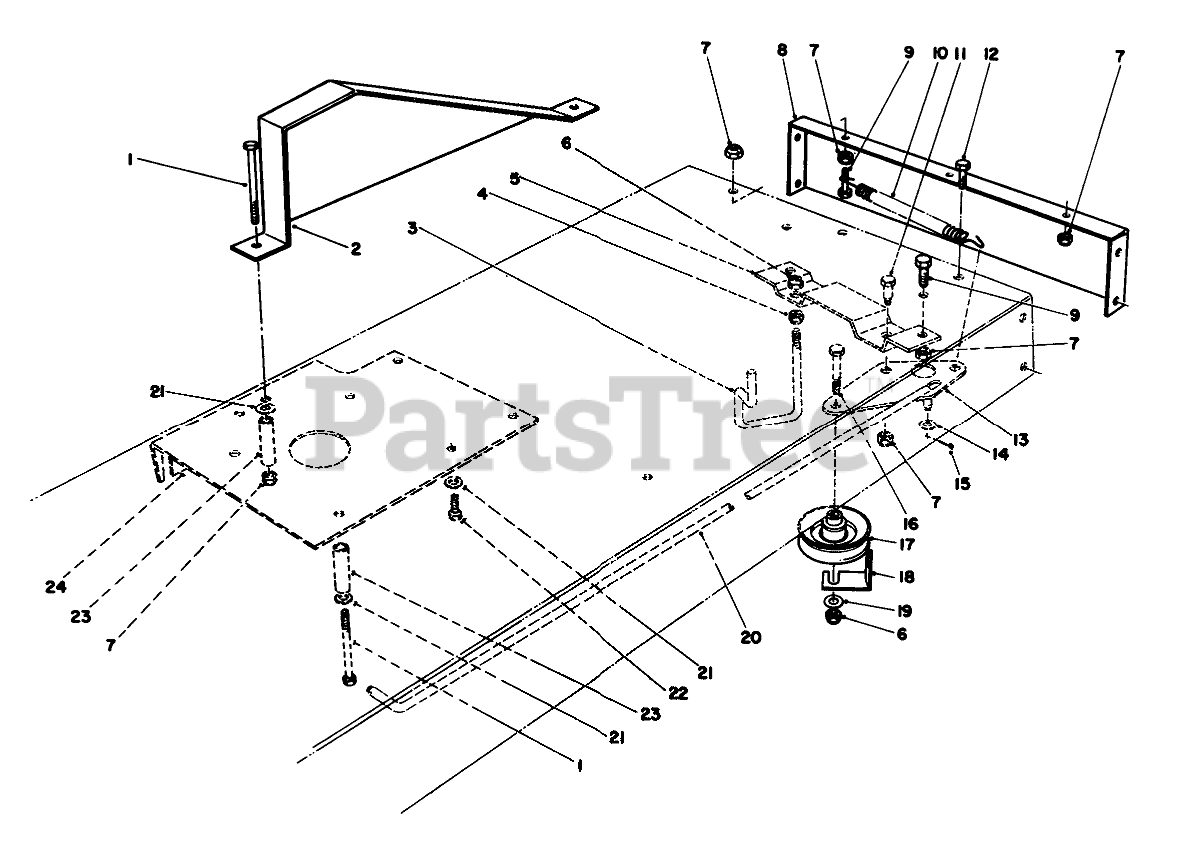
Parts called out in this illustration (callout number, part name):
1	SCREW-HH
2	CHAIN GUARD R
3	BELT GUIDE
4	NUT-LOCK, SIDE
5	TRACT SUPP BRKT B
6	NUT-LOCK, CONE
7	NUT-LOCK, NI
8	REAR FRAME R
9	SCREW-HH
10	TRACTION SPRING
11	BOLT-SHOULDER
12	SCREW-HH
13	TRACTION PIVOT BRKT
14	WASHER-FLAT
15	PIN-COTTER
16	SCREW-HH
17	PULLEY-IDLER
18	RETAINER-BELT
19	WASHER-FLAT
20	TRACTION ROD
21	WASHER-PLAIN
22	Screw-HH
23	OUTER TUBE SPACER
24	REINF PLATE R
